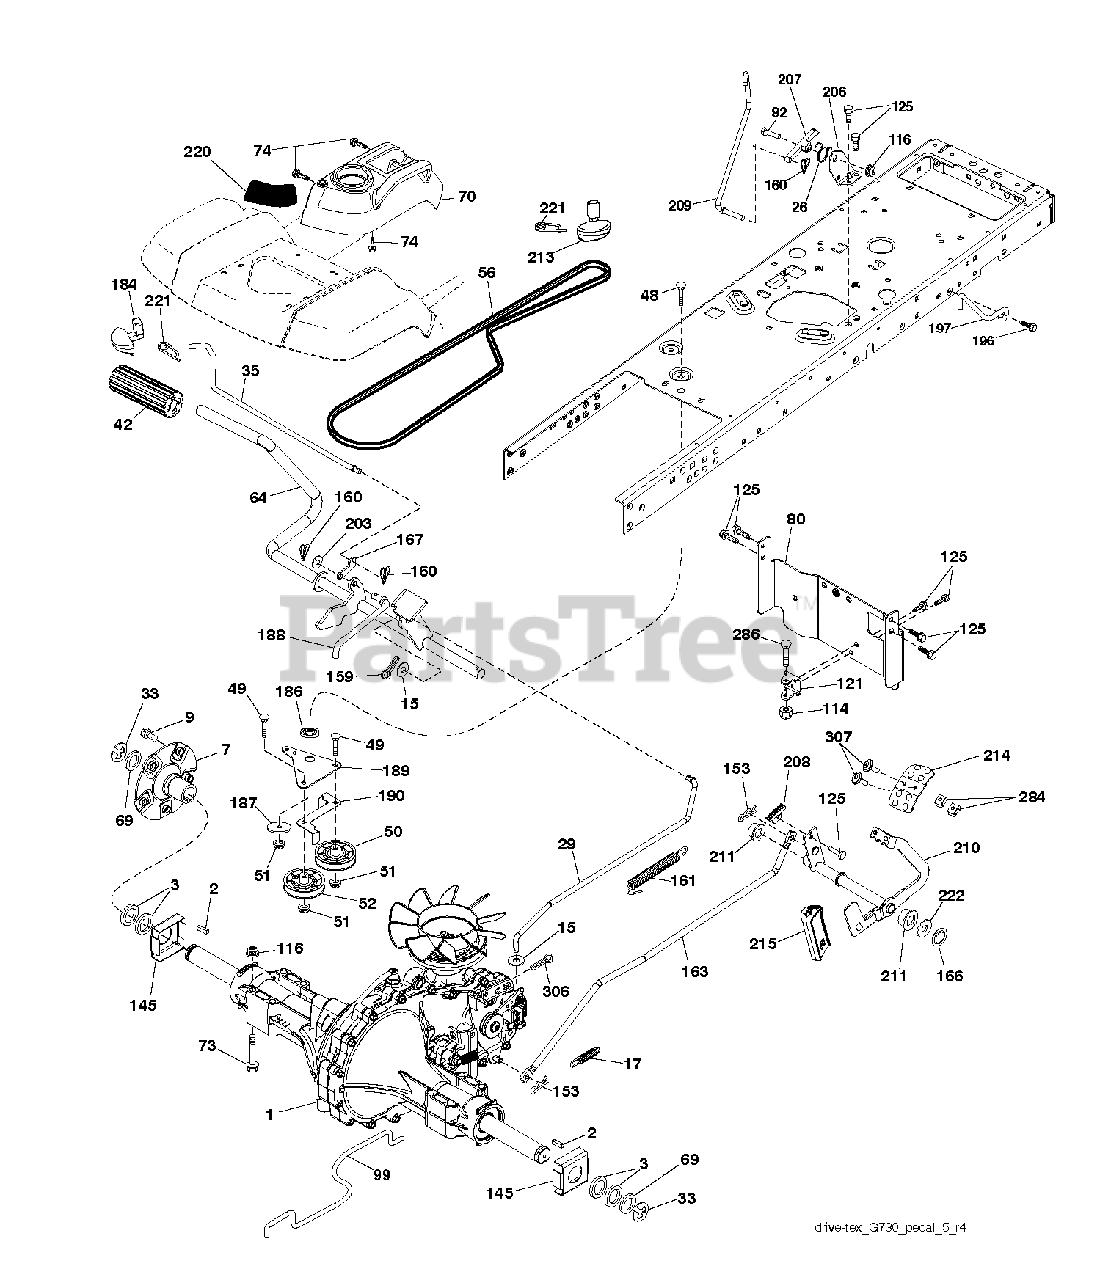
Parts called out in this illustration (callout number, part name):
2	KEY 1/4 X 2.5
7	HUB.ASM.WHEEL.REAR.23"TEX
15	WASHER
17	SPRING.BRAKE.HG3000/3500
26	SPRING.RETURN.CRUISE
33	E RING HYT
35	ROD.BRAKE.PARTK.HUSQ.TEX
42	PEDAL COVER T
48	BOLT.3/8-16X1.50
50	IDLER.FLAT.910.OFFSET
51	NUT LOCK FLG 3/8-16 UNC
52	IDLER.V-GROOVE.910.OFFSET
56	V-BELT.GROUND.DRIVE.
64	SHAFT.ASM.PEDAL.BRK.CNTR
70	CONSOLE.ASM.RH.GT.FC.HUSQ
73	BOLT HEX FLGHD 5/16-18X3 GR. 5
74	SCREW.HI-LO.CONSOLE
80	STRAP.TORQUE.YT.G700
92	BOLT
99	SPRING.BYPASS.YT.G700
114	NUT.71038.31-18.HEX.NYLOCK
116	NUT LOCK HEX FLANGE 5/16-18
121	BRACKET STRAP TORQUE
125	SCREW
145	WASHER.AXLE.FLANGE.HG-3000
153	RETAINER M
159	COTTER PIN
160	RETAINER CLIP
161	SPRING, RETURN LT
163	ROD PEDAL CONTROL
166	NUT.PUSH.625
167	LATCH.BRAKE.SPRING
184	RB HANDLE.PARKG.BRK.HUS/PRED
186	SPACER.RETAINER
187	WASHER 12/32X2X10GA
188	RP LINK.CLUTCH.GROUND.DRIVE
189	BELLCRANK.GROUND.DRIVE.TRAPPED
190	KEEPER BELLCRANK ROUND DRIVE
196	SCREW 3/8-16X1
197	BRKT.ANIT-ROTATION.CLUTCH
203	WASHER
206	BRKT.MOUNT.LATCH.CRUIS
207	LATCH.CONTROL.CRUISE
208	GEAR.SECTOR.CONTROL.CR
209	ROD.CONTROL.CRUISE.GT.
210	ROCKER.ASM.PEDAL.CONTR
211	BEARING.NYLON
213	KNOB.CONTROL.CRUSIE.HU
214	PEDAL.FORWARD.HUSQVARNA.DEALER
215	PEDAL.REVERSE.TEX.GT.4
220	REFLECTOR.RH.TEX GT
221	RETAINER.SPRING.CLIP.H
222	WASHER 21/32 X 1-1/4 X 10 GA.
284	NUT.U-CHNL.1/4-20.550DP.350PNL
286	BOLT.5/16-18X2.5
306	PIN COTTER
307	SCREW.MACHINE.CR.1/4-20
